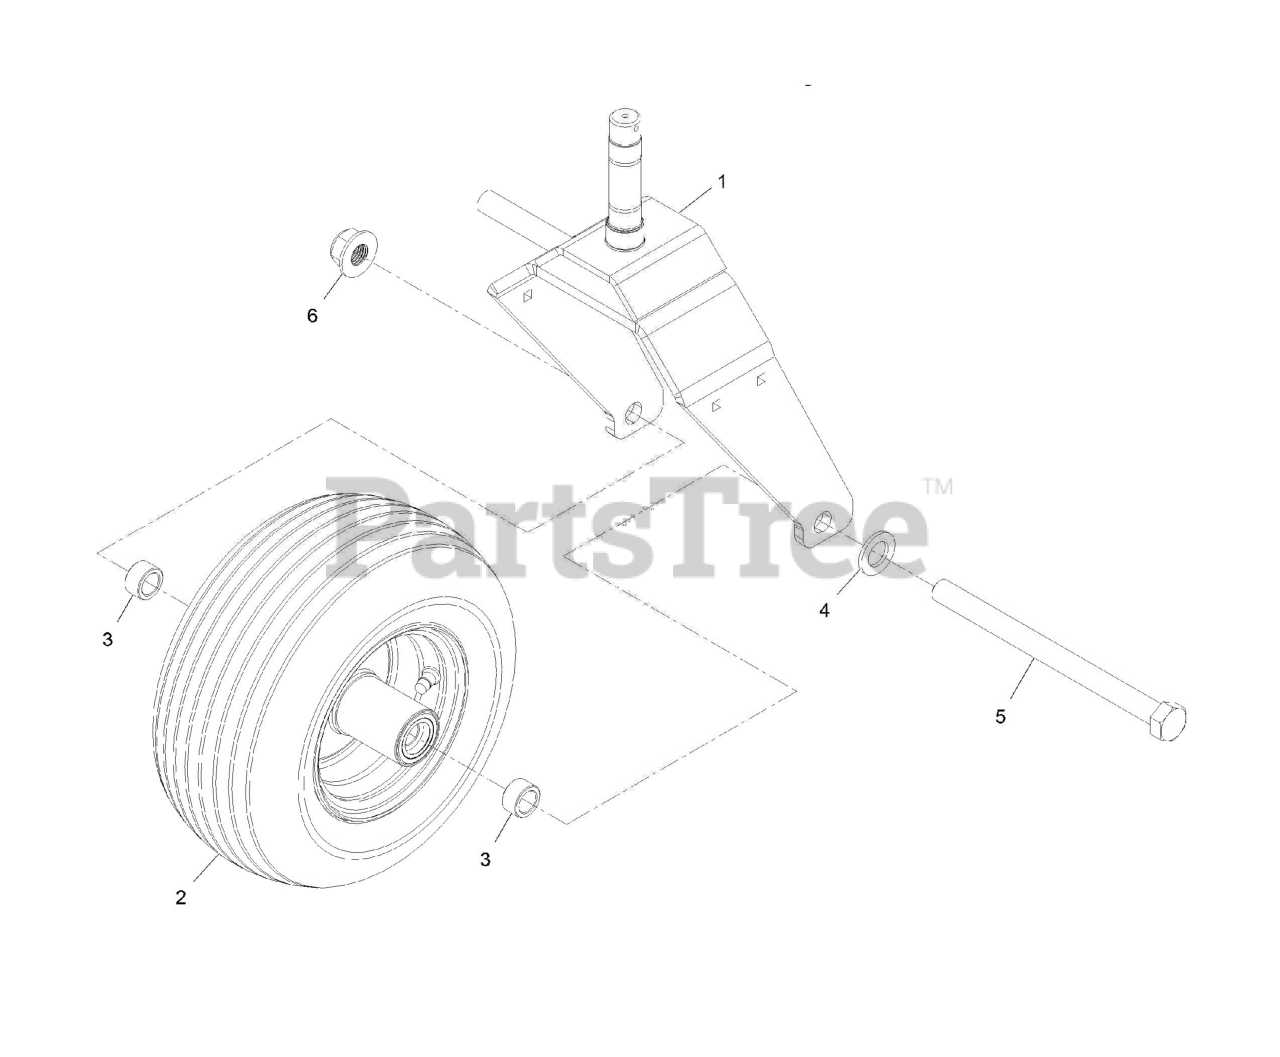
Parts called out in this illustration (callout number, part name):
1	Fork-Caster, LH [red]
2	WHEEL AND TIRE
3	SPACER-AXLE
5	SCREW-HH
